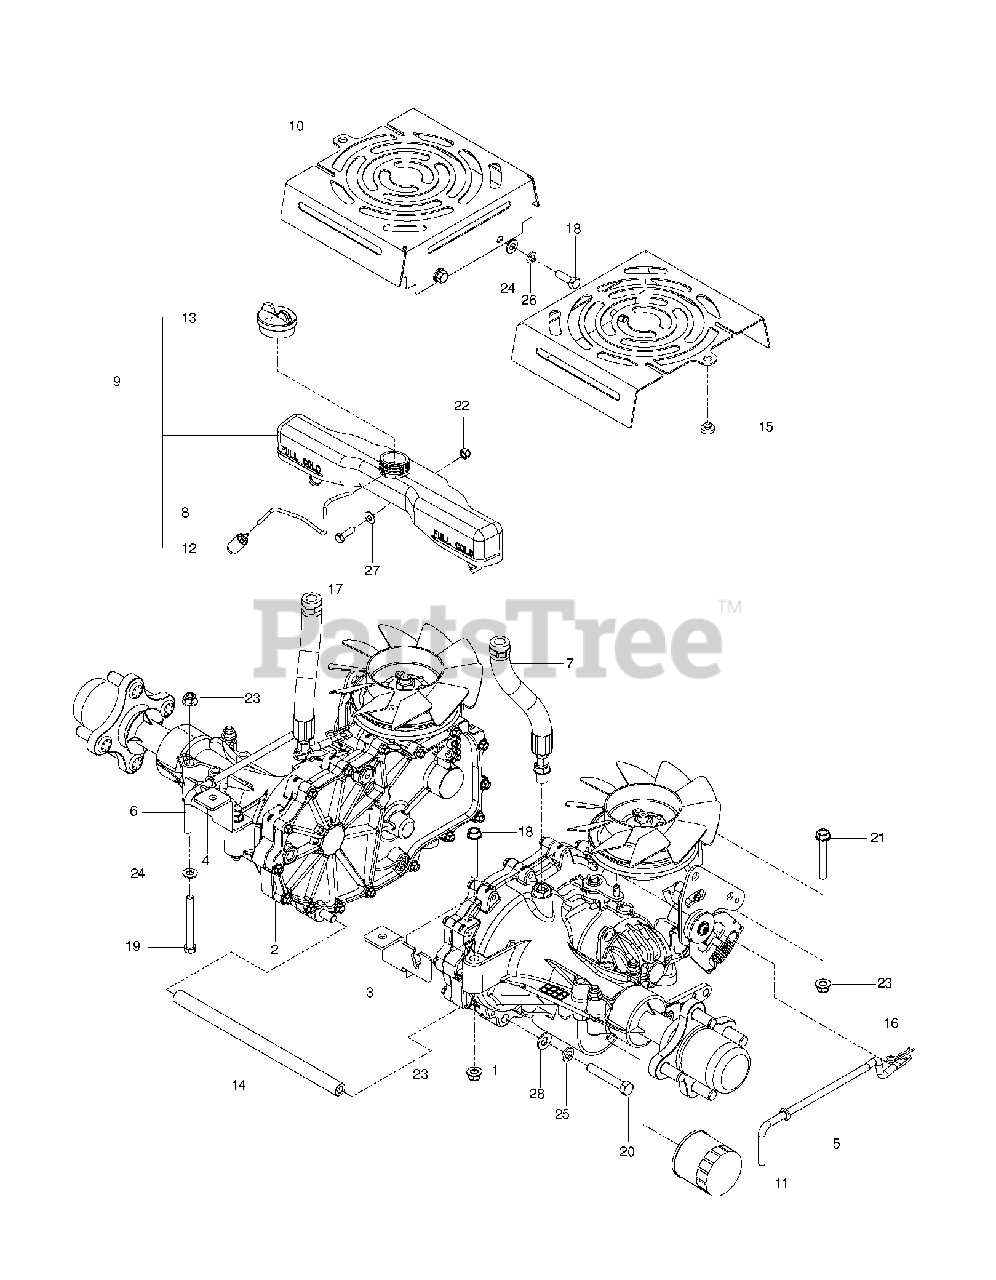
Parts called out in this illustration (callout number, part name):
1	HG_TRANS, ZT-3400, RT
2	HG_TRANS, ZT-3400, LT
3	BRACKET.TRANS.LT.BLACK
4	BRACKET, TRANS, RT BLACK
5	LINKAGE, LEFT BYPASS
6	LINKAGE, RIGHT BYPASS
7	HOSE ASSY, EXPANSION
9	TANK EXPANSION W/CAP
10	SHIELD FAN BLACK
11	HG_FILTER, ZT4800 52114
12	FUEL PICK-UP ASSY
13	CAP EXPANSION W/SEAL
14	TUBE, SPACER, 3400
15	GROMMET, BUMPER
16	HAIRPIN #2
17	HCS 1/4-20X7/8 GR5
18	HCS 5/16C X 1
19	HCS 5/16C X 2-3/4
20	HCS 3/8-16X2-1/4 LOC PATCH GR8
21	HHFS 5/16-18 X 2.25 GD 5
22	RP_NUT 1/4-20 NYLOC
23	5/16-18 NYLOC FLANGE NUT
24	FLAT WASHER 5/16 SAE
25	SLW 3/8 STD
26	WASHER 5/16 LOCK
27	WASHER 1/4 SAE
28	WASHER 3/8 SAE FLAT
